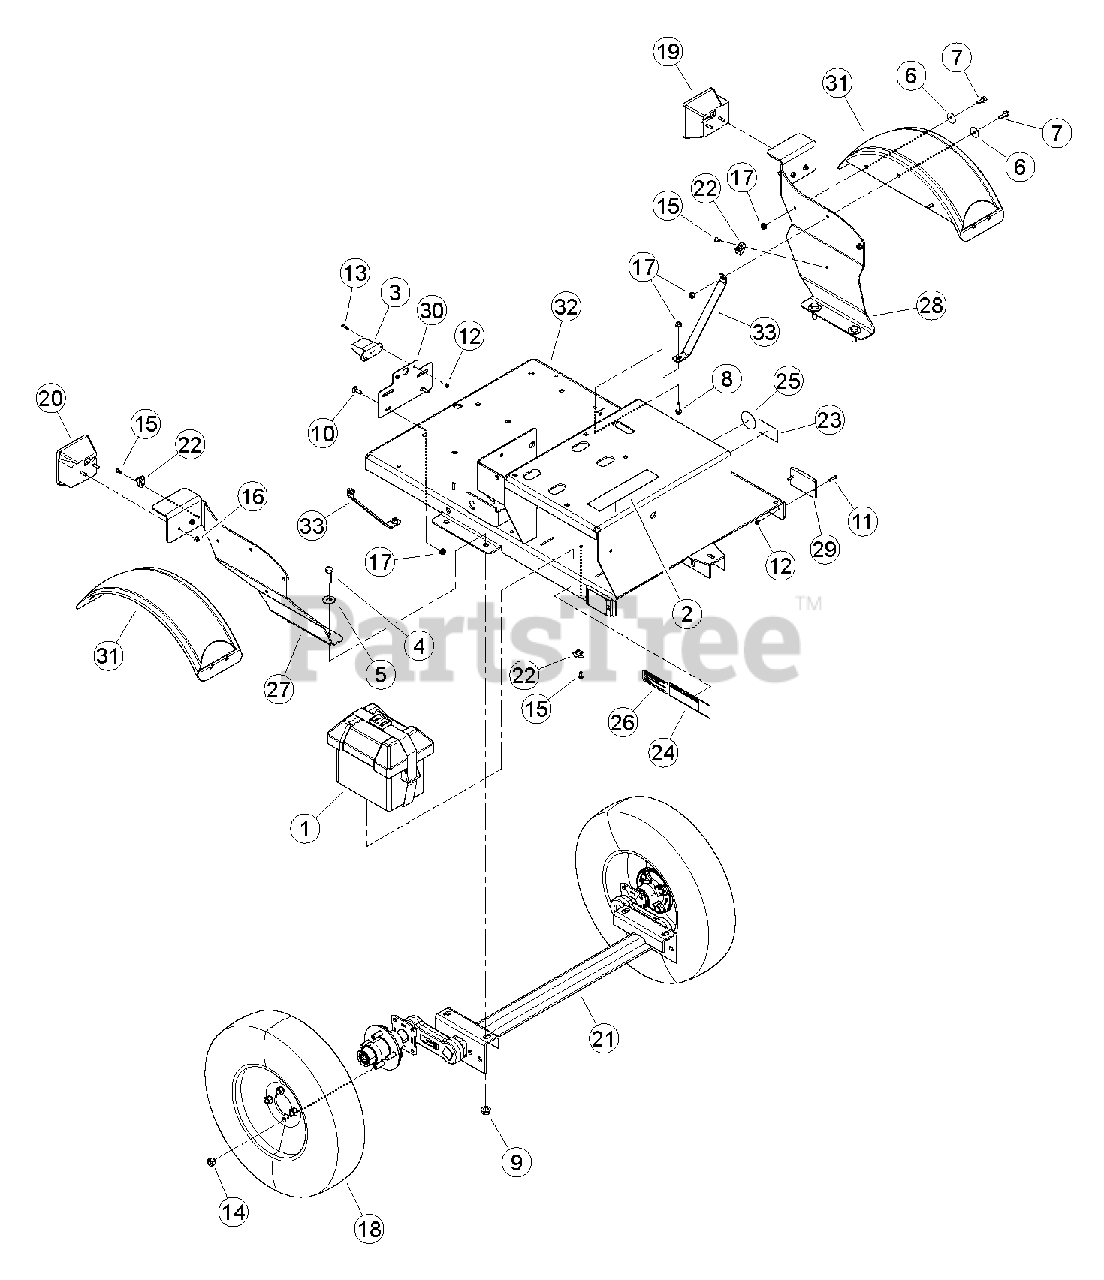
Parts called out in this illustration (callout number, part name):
1	BOX, SMALL BATTERY
2	DECAL, CHIPPER ENGAGEMENT
3	LIGHT, LICENSE PLATE
4	BOLT, 1/2-13 X 1-1/2 HEX HD GR5
5	WASHER, 1/2 FLAT
6	WASHER, 5/16" FENDER ZP
7	BOLT, 5/16 X 7/8 FLANGE NC
8	BOLT, 5/16 X 1 FLANGE NC
9	NUT, 1/2-13 NYLOCK FLANGE
10	BOLT, 5/16-18 X 1 GR5 CRG
11	SCREW, MCH 10-24 X 1" RND HD PHL ZP
12	NUT, 10/24 NYLOCK TYPE NM ZP
13	SCREW, MCH #10-24 X 3/4" PAN HD PH ZP
14	NUT, 1/2-20 WHEEL
15	RIVET, AL BLIND 1/4 X 3/4 DOME HEAD
16	NUT, 1/4-20 NYLOCK FLANGE
17	NUT, 5/16-18 NYLOCK FLANGE
18	ASSEMBLY, 5.30-12 TIRE + SPOKE RIM
19	LIGHT, LH TAIL
20	LIGHT, RH TAIL
21	AXLE, 1000 LB TORSION
22	CLAMP, CABLE MOUNT
23	DECAL, 5.30-12 LOAD RATING
24	DECAL, CHECK WHEELS
25	DECAL, NATM COMPLIANCE
26	DECAL, EPA EVAP
27	BRACKET, RH FENDER
28	BRACKET, LH FENDER
29	KIT, LED AMBER LIGHT
30	PLATE, LICENSE
31	FENDER, BLACK PLASTIC DRILLED
32	WELDMENT, C/S TRAILER
33	BRACE, FENDER
